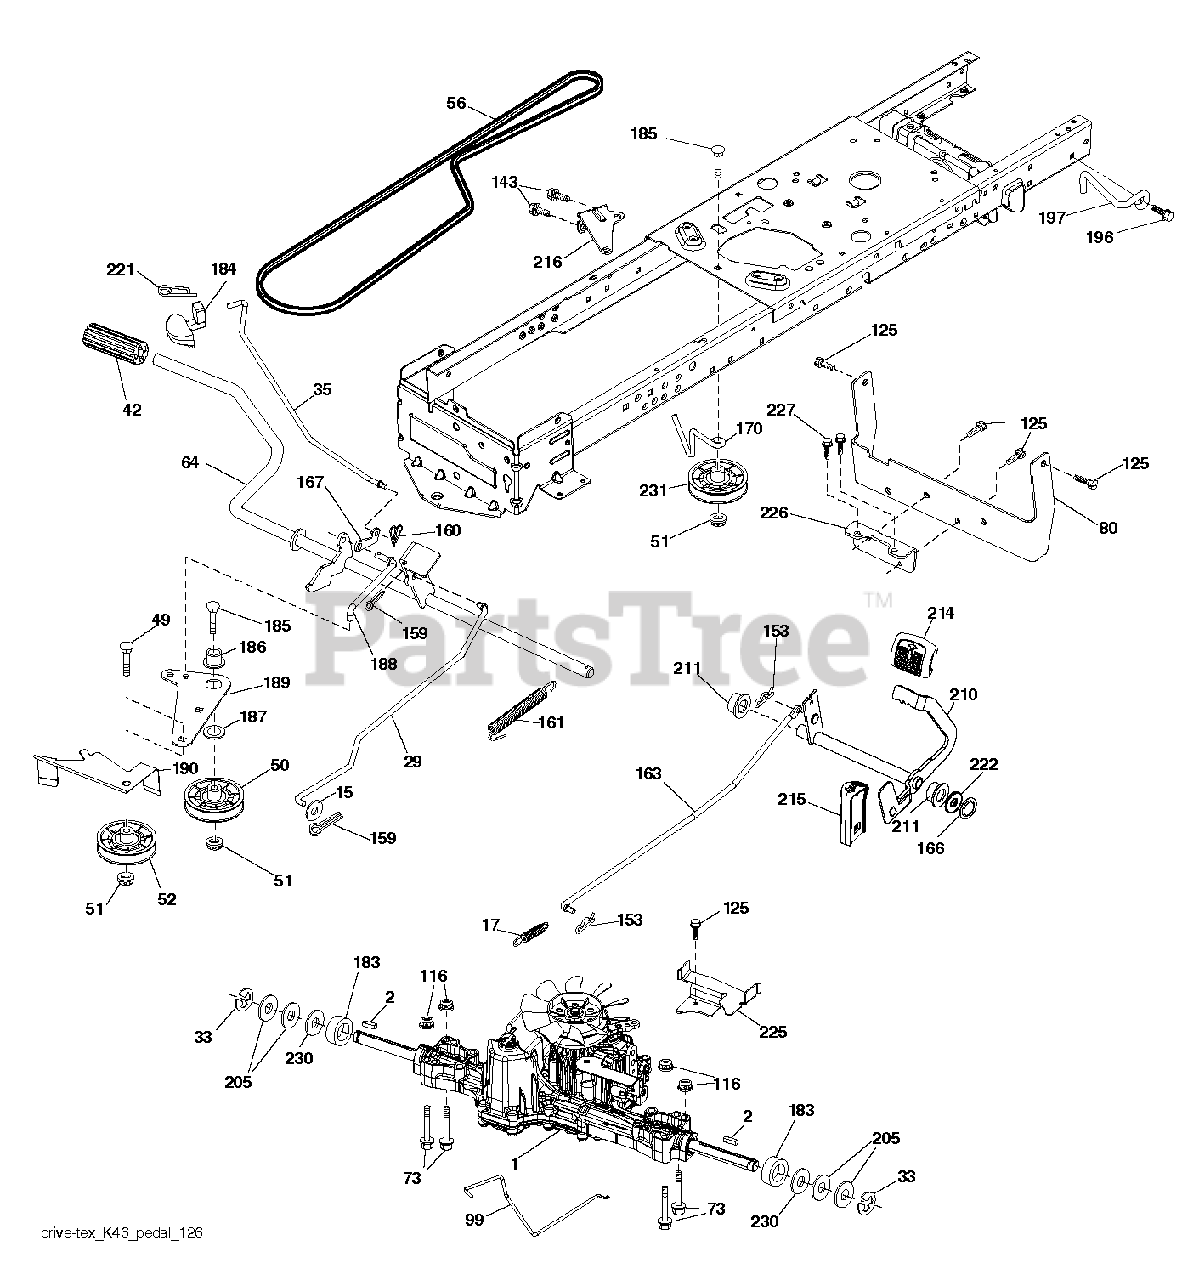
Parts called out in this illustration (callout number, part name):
2	SQUARE KEY
15	WASHER
17	SPRING.BRAKE.K46.GREEN
29	ROD.BRAKE.K46
35	ROD.CNTRL.PARK.PREDATOR.LT.TEX
42	PEDAL COVER T
50	IDLER.FLAT.910.OFFSET
51	NUT LOCK FLG 3/8-16 UNC
52	IDLER.V-GROOVE.910.OFFSET
56	V-BELT.MOWER.92.40.42/K46
64	SHAFT.ASM.PEDAL.BRK.CNTR
80	STRAP.TORQUE.K46.K57R.TT
99	ROD.SPRING.BYPASS.K46.LT.Z
116	NUT LOCK HEX FLANGE 5/16-18
125	SCREW
143	SCREW LT
153	RETAINER M
159	COTTER PIN
160	RETAINER CLIP
161	SPRING, RETURN LT
163	ROD.CONTROL.K57R.K46
166	NUT.PUSH.625
167	LATCH.BRAKE.SPRING
170	KEEPER.CENTER SPAN.1.688
183	SPACER AXLE
184	HANDLE.PARKING.BRK.PRED.LT.RED
186	SPACER.RETAINER
187	WASHER 12/32X2X10GA
188	RP LINK.CLUTCH.GROUND.DRIVE
189	BELLCRANK.GROUND.DRIVE.TEX.
190	KEEPER.BELLCRANK.DRIVE
196	SCREW 3/8-16X1
197	LINK.CLUTCH.ANIT-ROTAT
210	ROCKER.ASM.PEDAL.CONTR
211	BEARING.NYLON
214	PEDAL.FORWARD.PAD.TEX
215	PEDAL.REVERSE.TEX.GT.4
216	BRACKET.PULLEY.IDLER.W/TEX
221	RETAINER.SPRING.CLIP.H
222	WASHER 21/32 X 1-1/4 X 10 GA.
225	KEEPER.BELT.TRANSAXLE.K46
226	BRACKET.MOUNT.TORQUE.K46.TLT
227	SCREW
230	WASHER.HARDENED
231	IDLER.V-GROOVE.1.688.OFFSET
